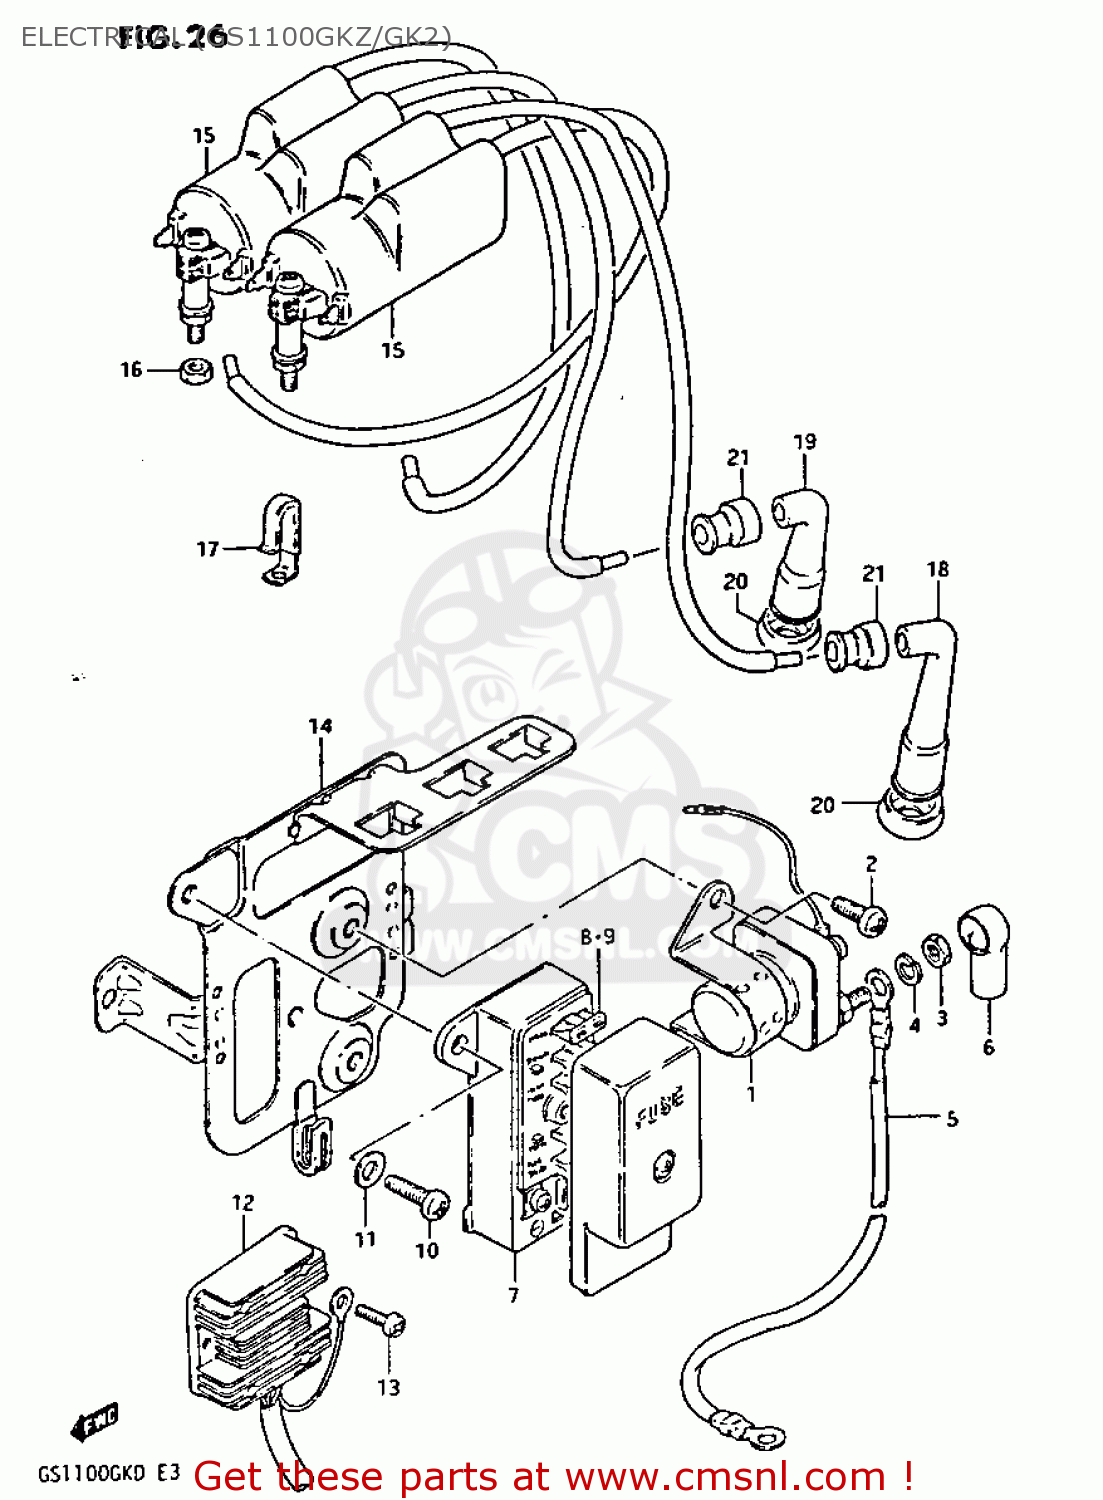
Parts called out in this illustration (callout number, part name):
1	RELAY ASSY,STARTING MOTOR
2	SCREW
3	NUT 6MM
4	WASHER,LOCK
5	CABLE,STARTING MOTOR
6	CAP,TERMINAL
7	BOX ASSEMBLY,FUSE
8	FUSE(10A)
9	FUSE(15A)
10	SCREW 6X12
11	WASHER
12	RECTIFIER ASSEMBLY
13	SCREW 6X12
14	HOLDER COMP,ELECTRONIC PARTS
15	COIL ASSEMBLY,IGNITION
16	NUT
17	CLAMP
18	CAP ASSY,SPARK PLUG
19	CAP,SPARK PLUG
20	SEAL,SPARK PLUG
21	SEAL,SPARK PLU
